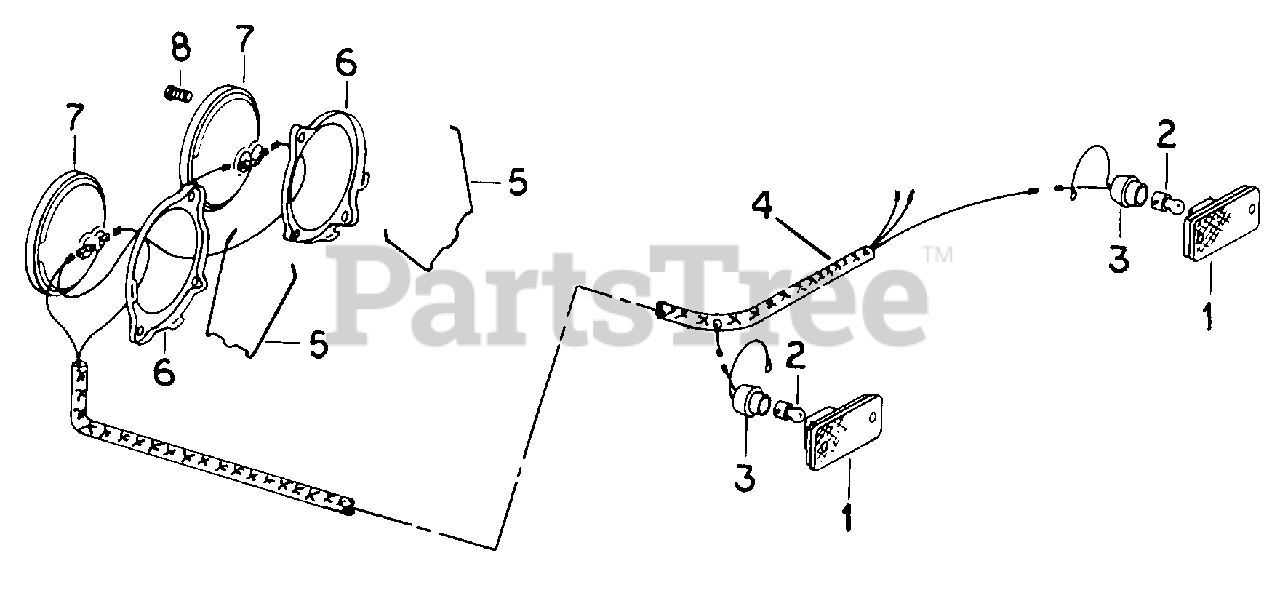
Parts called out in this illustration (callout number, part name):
1	Lens Assy, Taillight
2	Lamp, Type C-2F Trade #194
3	Cable Assy, Taillight
4	Harness Assy, Main Cable
5	Spring, Headlamp Retaining
6	Retainer, Headlamp
7	Light, Sealed Beam Head
8	Screw, Headlight Mtg
